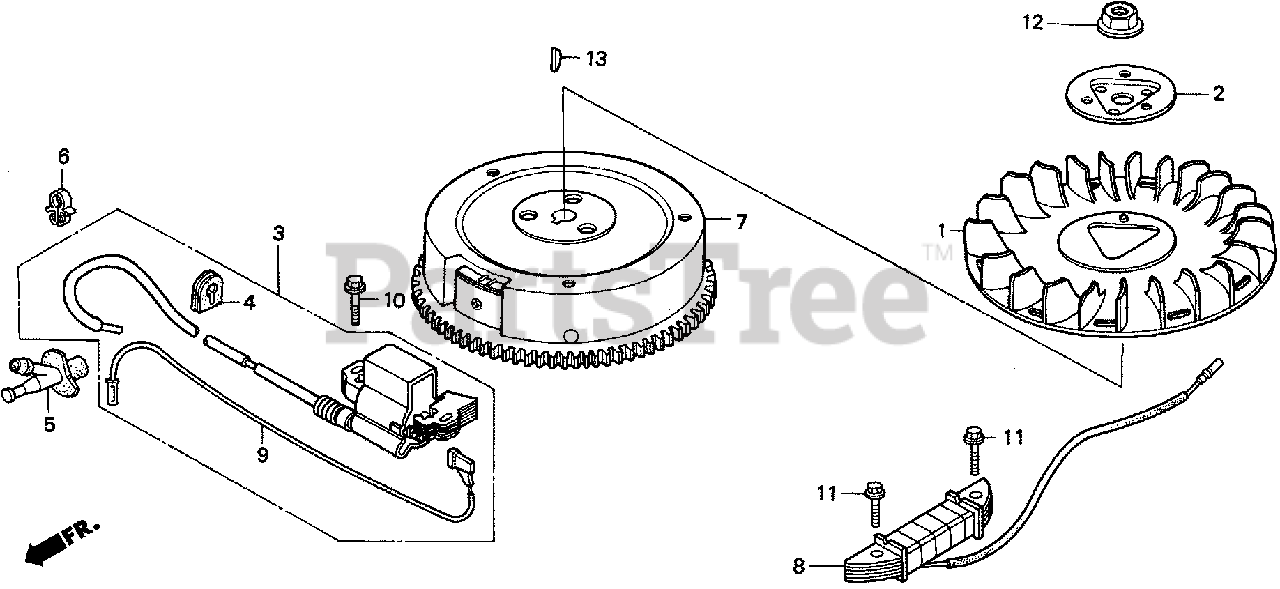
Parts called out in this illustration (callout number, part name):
1	FAN, COOLING
2	PLATE, COOLING FAN SETTING
3	COIL ASSY., IGNITION
4	GROMMET, IGNITION
5	CAP ASSY., NOISE SUPPRESSOR
6	CLIP, IGNITION WIRE (8MM)
7	FLYWHEEL (SEL-4POLE)
8	COIL ASSY., CHARGE (3A)
9	WIRE, STOP SWITCH
9	WIRE, STOP SWITCH (NOT AVAILABLE)
10	BOLT, FLANGE (6X28) (CT200)
11	BOLT, FLANGE (6X32) (CT200)
12	NUT, SPECIAL (16MM)
13	KEY, SPECIAL WOODRUFF (25X18)
